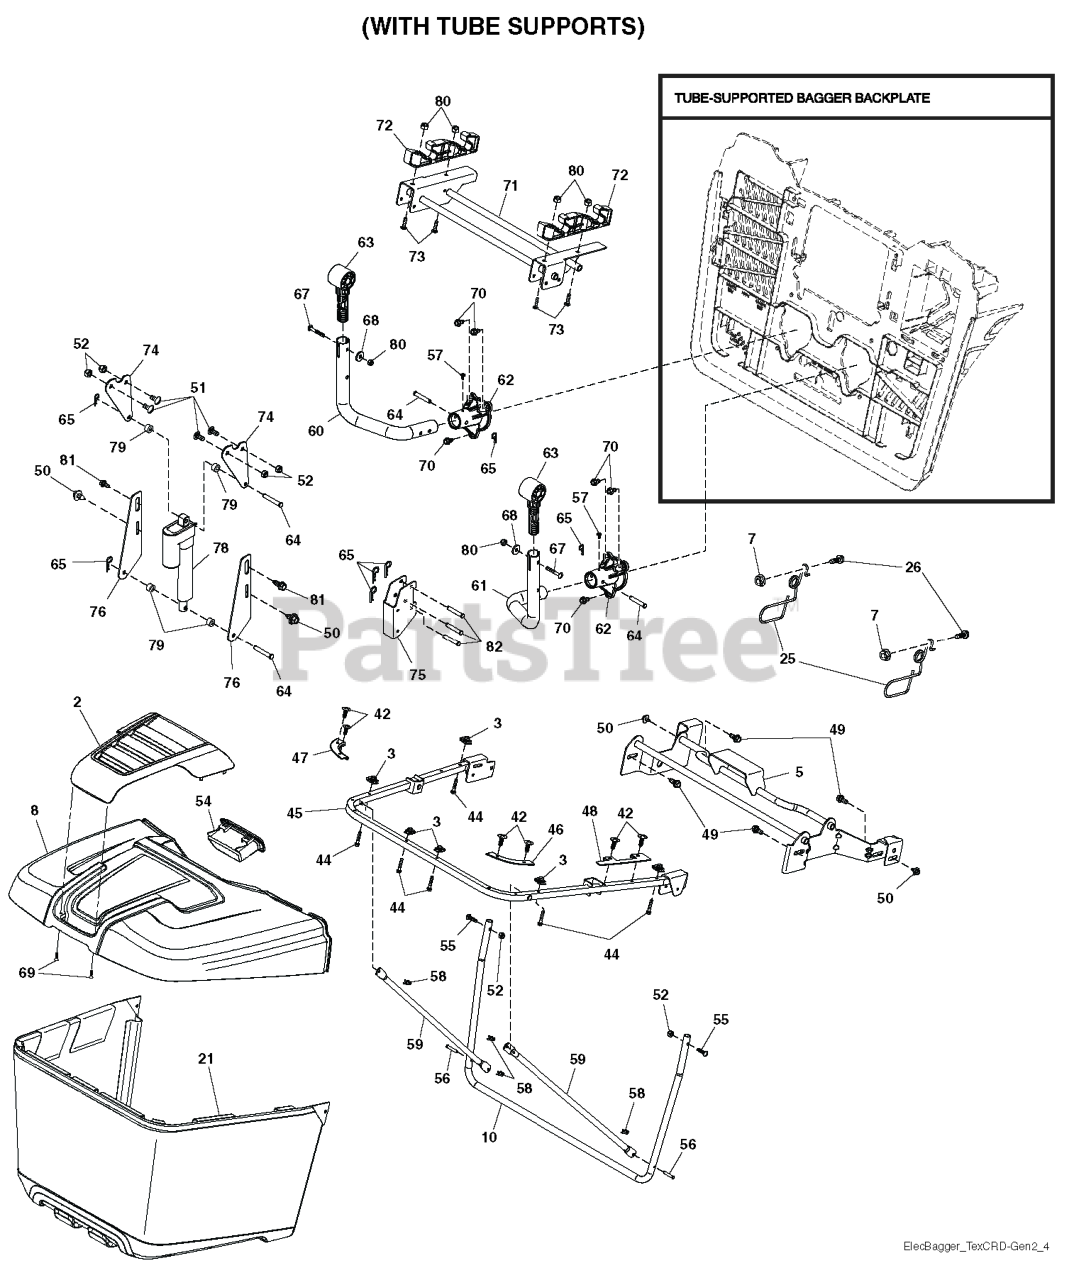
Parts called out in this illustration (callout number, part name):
2	APPLIQUE.BAGGER
3	1/4-20 U NUT
7	NUT T
10	FRAME TEX_CRD_GEN2 BAGGER FRAM
21	BAG FRAME BAGGER ASSEMBLY. HUS
25	LATCH LATCH. BAG. CRD GEN 2
26	SCREW HEX CRT
42	CLIP CHRISTMAS TREE CLIP
45	FRAME TEX_CRD_GEN2 UPPER U FRA
46	CONNECTOR RIGHT BAGGER CORNER
47	CONNECTOR LEFT BAGGER CORNER C
48	BAFFLE BAGGER SIDE CLOSE-OUT
49	BOLT, SHOULDER 5/16-18
50	BOLT.5/16-18UNCX3/4 W/SEMS.BLK
51	BOLT.CARR.SQNK.5/16-18UNC.X3/4
52	NUT.71038.31-18.HEX.NYLOCK
54	HANDLE BAGGER TOP FRONT HANDLE
55	BOLT
56	PIN.CLEVIS.183
57	SCREW T-30 1/4-20 X
58	RETAINER CLIP PM
59	TUBE BAGGER SPREADER TUBE, TEX
63	BAGGER.PIVOT.ELECT.DUMP.TEXCRD
65	RETAINER M
69	SCREW,#8.FLAT.HEAD.DRILL.TIP
70	SCREW, 3/8-16X3/4
73	BOLT.CARRIAGE.5/16-18
79	SPACER.NYLON.75" X .4375
80	NUT LOCK HEX FLANGE 5/16-18
81	SHOULDER BOLT 5/16-18TT
